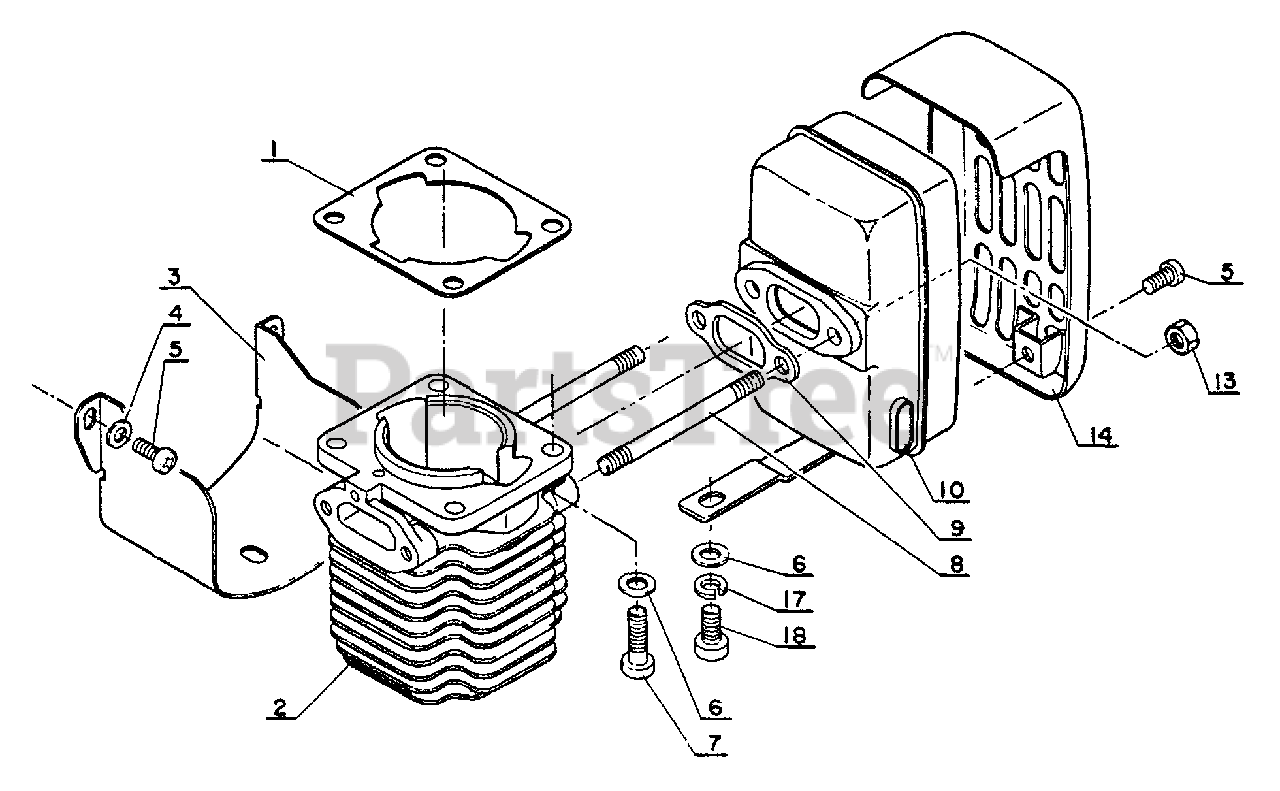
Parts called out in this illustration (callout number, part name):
1	GASKET, CYLINDER
2	CYLINDER
3	SHIELD, CYLINDER
4	WASHER 4 MM
5	SCREW - 4×8
6	WASHER, FLAT 5.5×10×0.8
7	SCREW 5×16
8	STUD
9	GASKET, MUFFLER
10	MUFFLER
13	LOCKNUT - 5
14	COVER, MUFFLER
17	WASHER, SPRING 5
18	SCREW 5×10
